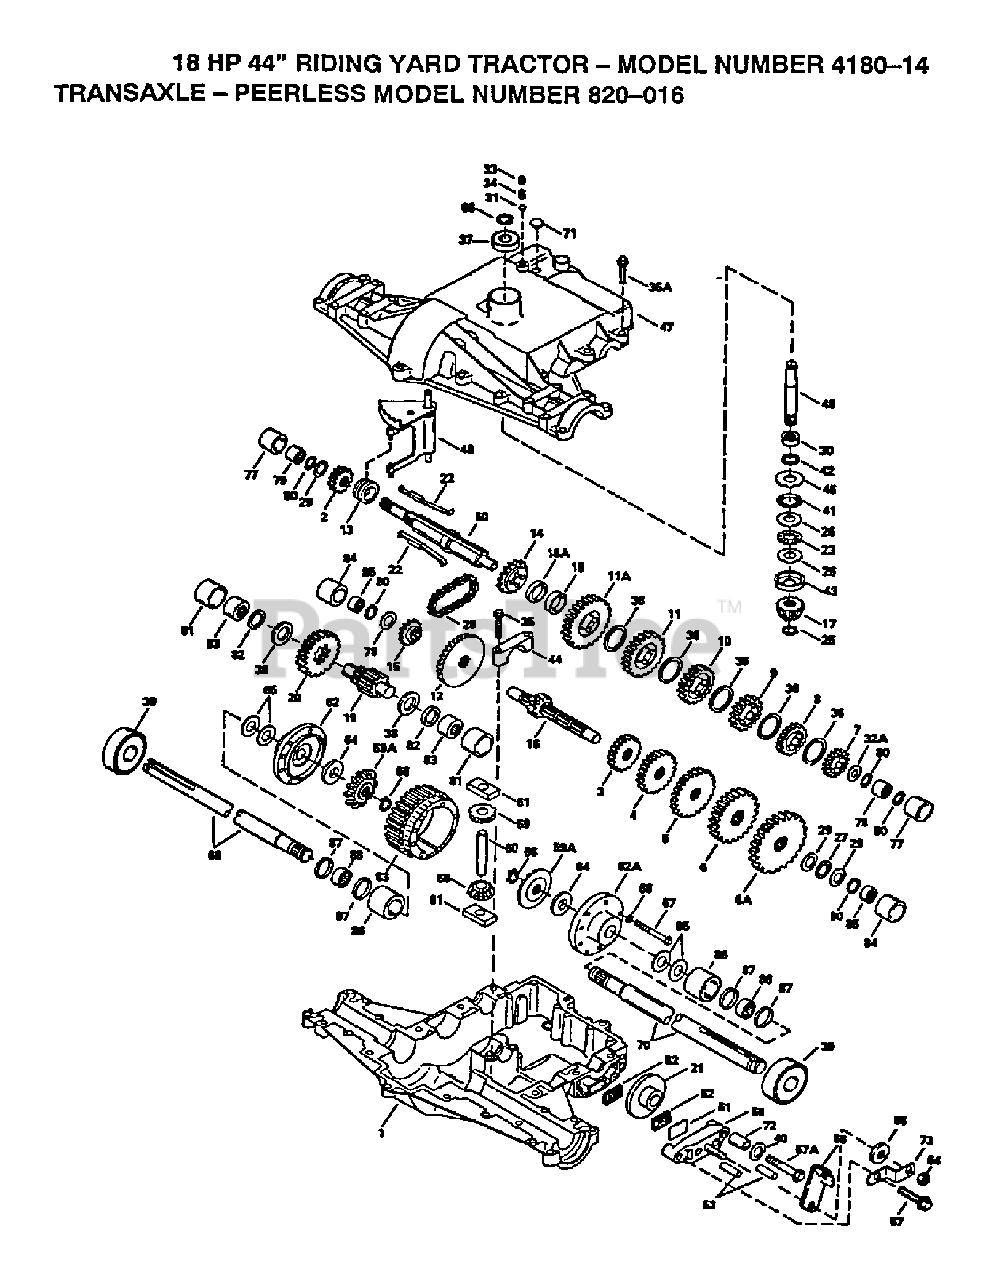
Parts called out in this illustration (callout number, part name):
8	Poulan TBD
10	Poulan TBD
11	Poulan TBD
11A	Poulan TBD
85	Oil Seal
